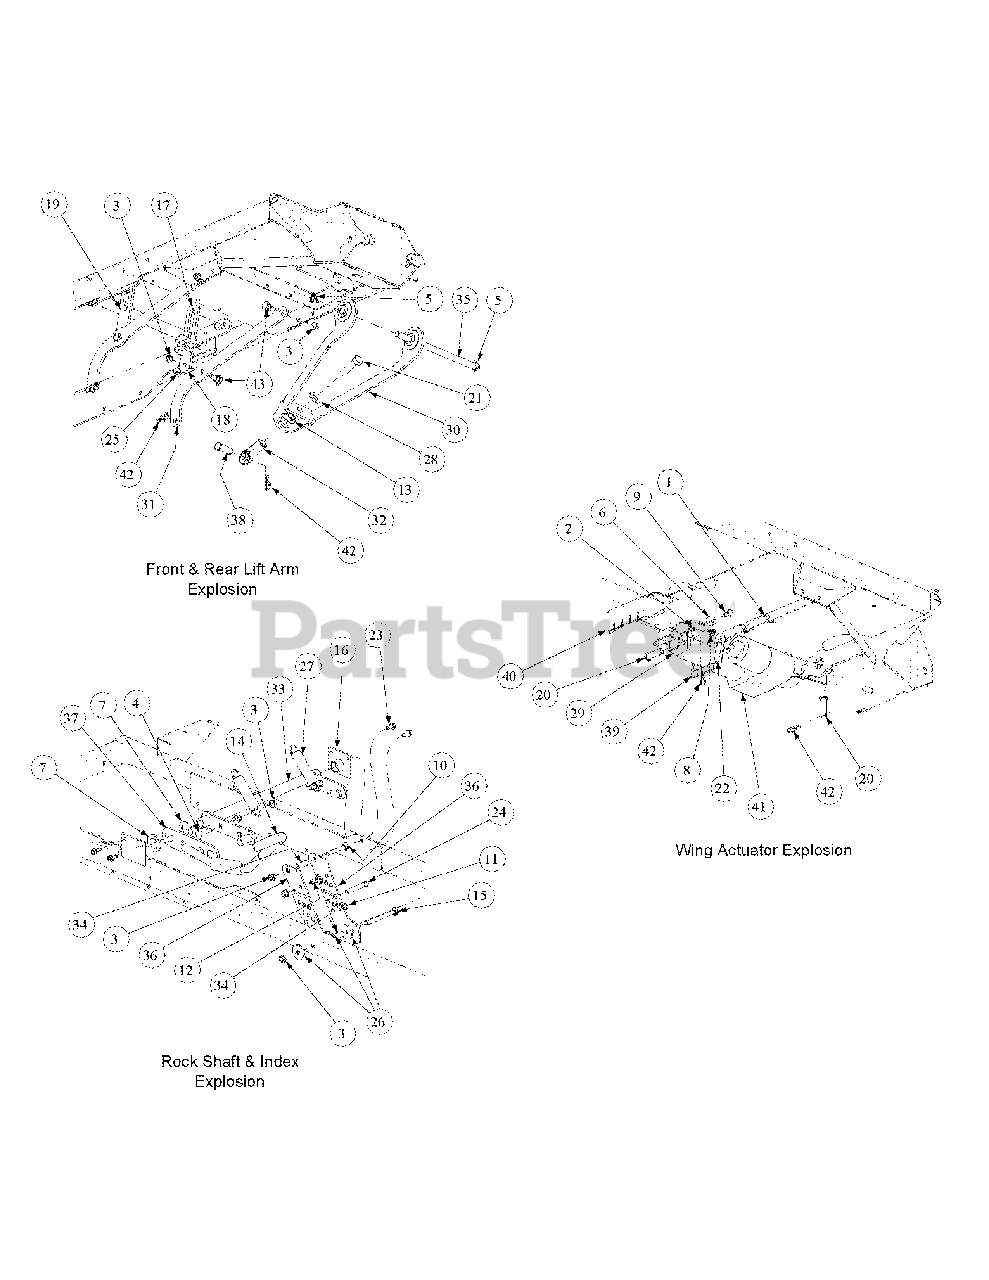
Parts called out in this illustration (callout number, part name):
1	Hex Cap Screw, 5/16-18 x 3/4
2	Nut, 1/4-28, SS, Nylon Insert
3	Flange Lock, Hex Nut, 3/8-16
4	Carriage Bolt 3/8-16 x 1.50
5	Cotter Pin, 3/16 x 1-1
6	Spacer, Control Rod
8	Nut, Lock, Hex Flange, 5/16-18
9	Shoulder Screw, 1/4-28
10	Carriage Bolt 3/8-16 x 2.50
11	Cotter Pin, .148 x 3.00
12	Shoulder Screw, .50 OD x 0.27
13	Jam Nut, 5/8-18
14	Lift Handle Grip
15	Carriage Bolt, 3/8-16 x 4.00
16	Lift Hub Assembly
17	Upper Link Lift Assembly, Left Hand
18	Lower Lift Bracket, Left Hand
19	Link Lift PLate, Right Hand
20	Clevis Pin, .500 Dia. x 1.75 Lg.
21	Hex Cap Screw, 5/8-18 x 2.00
22	Battery Edge Trim
23	Self Tapping Screw, 5/16-18 x 3/4
24	Clevis Pin, .438 Dia. x 2.625 Lg.
25	Jam Nut, 1/2-20
26	Washer, 5/16-18
27	Extension Spring, .98 OD x 5.00
28	Washer, 5/8
29	Bracket Cable Weldment
30	Lift Front Arm Assembly
31	Rear Lift Arm
32	Rod End, 5/8, RH
33	Lift Shaft Assembly
34	Spacer, .375 x .5 x 1.176 Lg.
35	Front Lift Rod
36	Lift Index Plate
37	Lift Handle Assembly
38	CLevis Pin, 5/8 Dia.
39	Actuator Mounting Bracket
40	Cable Mounting Bracket Assembly
42	Hair Pin
43	Shoulder Screw, 3/8-16, .56 x .27
